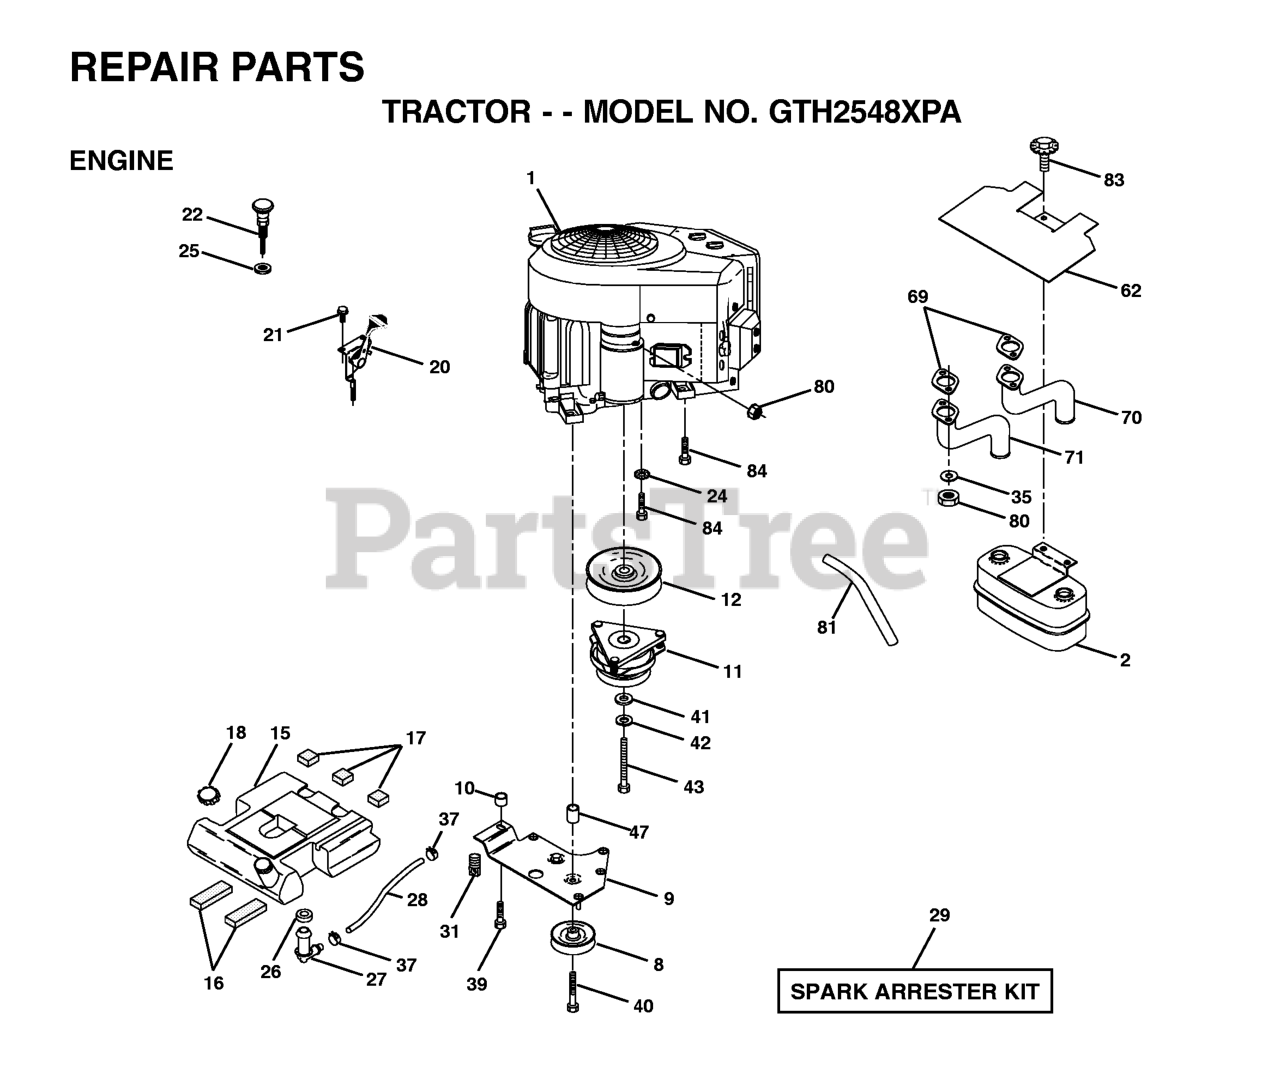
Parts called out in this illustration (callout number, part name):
2	MUFFLER.TWIN.CYL.LOW.TONE
8	RP.IDLER GROOVED
9	KEEPER ASM BELT ENGINE
11	CLUTCH
12	PULLEY ENG VGT ELECT CLUTCH
15	TANK.FUEL.5.0 LEFT.FILL.YTGT
16	PAD IDLER TI
17	PAD-SPACER LT
18	TANK CAP
20	CONTROL.THROTTLE.COBRA.42"BLK.
21	SCREW
22	CHOKE CONTROL
24	LOCKWASHER
25	Nut Keps 3/8 - 24 UNF
26	BUSHING OUTLET T
27	STEM FUEL TANK
28	HOSE
29	KIT.SPARK ARRESTOR 794945 B&S
37	HOSE CLAMP
39	SCREW TT 3/8-16X2-1/4 UNC
40	Screw TT 3/8-16 x 4 unc
42	LOCKWASHER
43	BOLT HEX 7/16-20 X 3.75 GR. 5
62	HEAT SHIELD
70	TUBE EXHAUST LH
71	TUBE.EXHAUST.KAWASAKI.RH
80	FLANGE NUT
81	TUBE, DRAIN OIL ASM.
83	BOLT.5/16-18UNCX3/4 W/SEMS.BLK
84	SCREW 3/8-16 X 1-1/2
